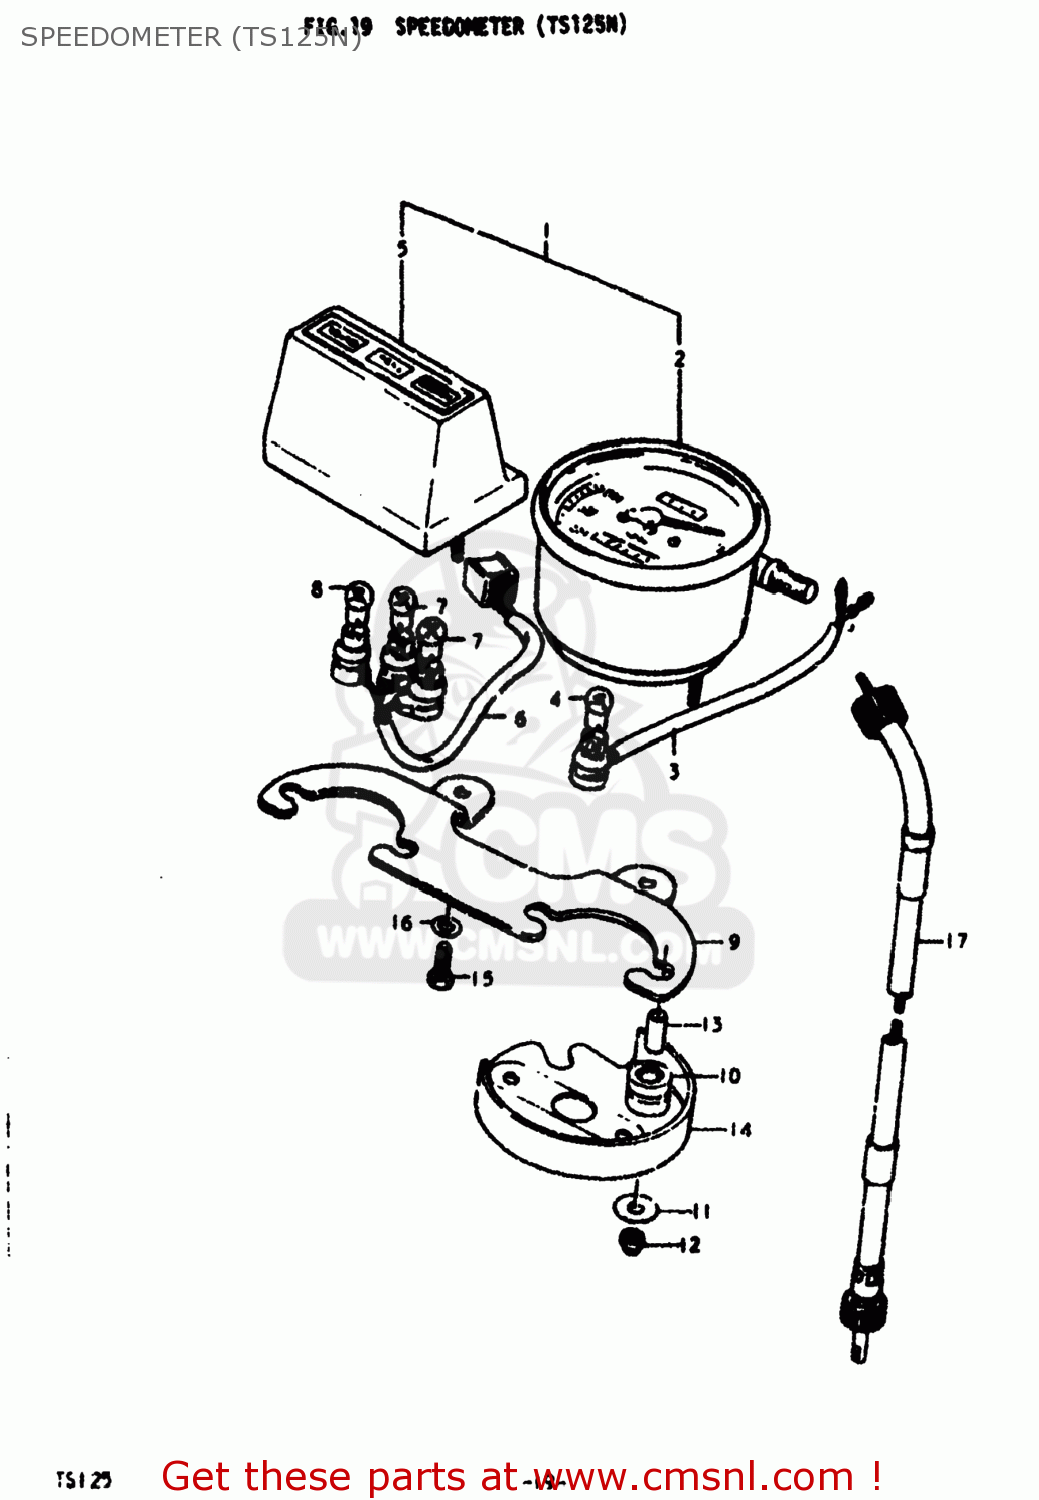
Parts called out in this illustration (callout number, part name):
1	SPEEDOMETER ASSEMBLY
2	SPEEDOMETER ASSEMBLY
3	SOCKET,SPEEDOMETER
4	BULB(6V/3W)
5	CASE,PILOT BULB
6	SOCKET
7	BULB(6V/3W)
8	BULB(6V1.7W,STANLEY,A61A)
9	BRACKET,COMBINATION METER
10	CUSHION,METER
11	WASHER (5.5X16X1.2)
12	NUT
13	SPACER,METER
14	COVER,METER,UNDER
15	BOLT, UPPER
16	WASHER
17	CABLE ASSEMBLY,SPEEDOMETER
